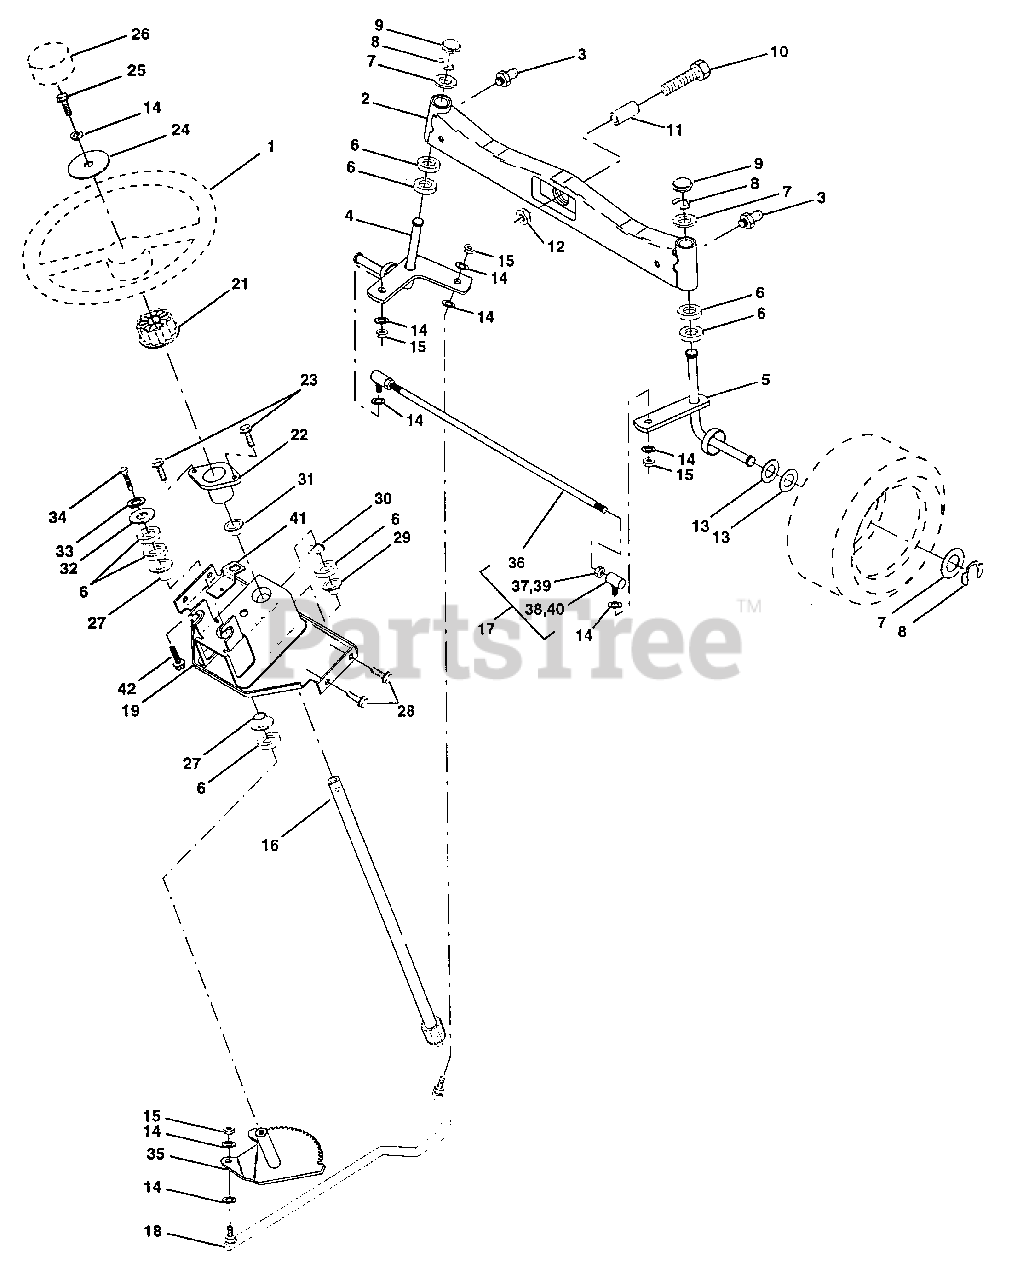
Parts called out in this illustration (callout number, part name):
1	Wheel, Steering (AYP part number)
2	Axle Asm., Front (AYP part number)
3	Fitting, Grease
4	Spindle Asm, LH
5	Spindle Asm., RH
6	Bearing, Race Thrust Harden
7	Washer 25/32 x 1-5/8 x 16 Ga.
8	Ring, Klip #T5304-75
9	Cap, Spindle
10	Bolt, Fin Hex 5/8-11 x 2-3/4
11	Spacer Brg Axle Front 1.570
12	Nut, Lock Flange 5/8-11 Unc
13	Washer 25/32 x 1-1/4 x 16 Ga.
14	Washer, Lock Hvy Hlcl Spr 3/8
15	Nut Lock Center 3/8-24 Unf
16	Shaft Asm., Steering
17	Rod Asm., Tie Ball J Ball Vgt
18	Draglink, Ball Joint Solid Vgt (AYP part number)
19	Support Asm., Steering Vgt
21	Adapter, Wheel Steering
22	Bushing, Strg.
23	Screw
24	Washer 13/32 x 2-3/8 x 8 Ga.
25	Bolt, Fin Hex 3/8-16 x 1 Gr. 5
26	Cap, Wheel Steering
27	Bearing, Col. Strg.
28	Screw Thdrol. 3/8-16 x 3/4 TY-TT
29	Bearing, Flange
30	Ring, Klip Truarc #5304-75
31	Bushing, Nyliner Snap
32	Washer 11/32 x 1 x 10 Ga.
33	Washer, Lock Hvy Hlcl Spr 5/16
34	Bolt, Hex Hd 5/16-18 x 3/4
35	Gear, Sector Steering
36	Tie Rod (AYP part number)
37	Jam Nut RH Thread
38	Joint Asm. Ball RH Thread
39	Jam Nut LH Thread
40	Joint Asm. Ball LH Thread
41	Bracket Switch Inerlock VGT97
42	Screw Thdrol 5/16-18 x 1/2 TYT
